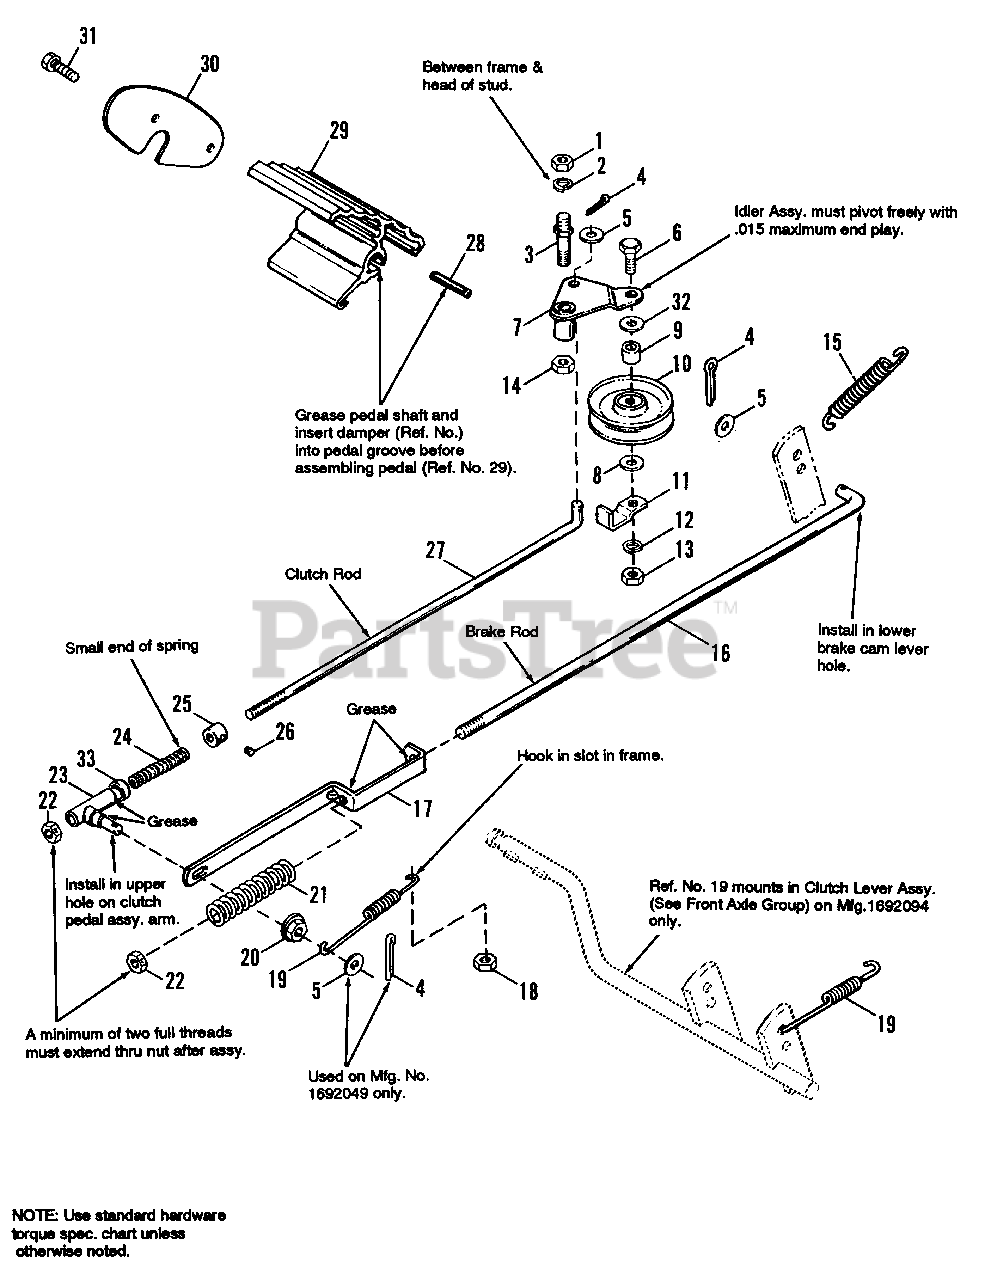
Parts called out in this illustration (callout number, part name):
1	NUT, Hex, 7/16-14
2	LOCKWASHER, 7/16
4	PIN, Cotter (Qty. 2 used on 1692094)
5	WASHER, 11/32
6	CAPSCREW, 3/8-16 x 1-1/2
7	IDLER ASSY.
8	WASHER, Plain, 5/16
10	PULLEY ASSY.
11	GUARD, Spring
12	LOCKWASHER, 3/8
13	NUT, Hex, 3/8-16
14	LOCKNUT, Hex, 7/16-14
15	SPRING, Tension
18	LOCKNUT, Hex (Used on 1692049 only)
19	SPRING, Return
20	LOCKNUT, Hex, Flange, 5/16-18
21	SPRING, (Used on 1692049 only)
21	SPRING, (Used on 1692094 only)
22	LOCKNUT, 5/16-18
23	GUIDE ASSY., Rod
24	SPRING, Compression
25	COLLAR, Set
26	SETSCREW, 1/4-20 x 3/8
27	ROD, Clutch
28	DAMPER, Rubber
29	PEDAL, Foot
30	PLATE, End
31	SCREW, Taptite, 1/4-20 x 5/8
32	WASHER, Plain
33	SPACER, (Used on 1692094 only)
